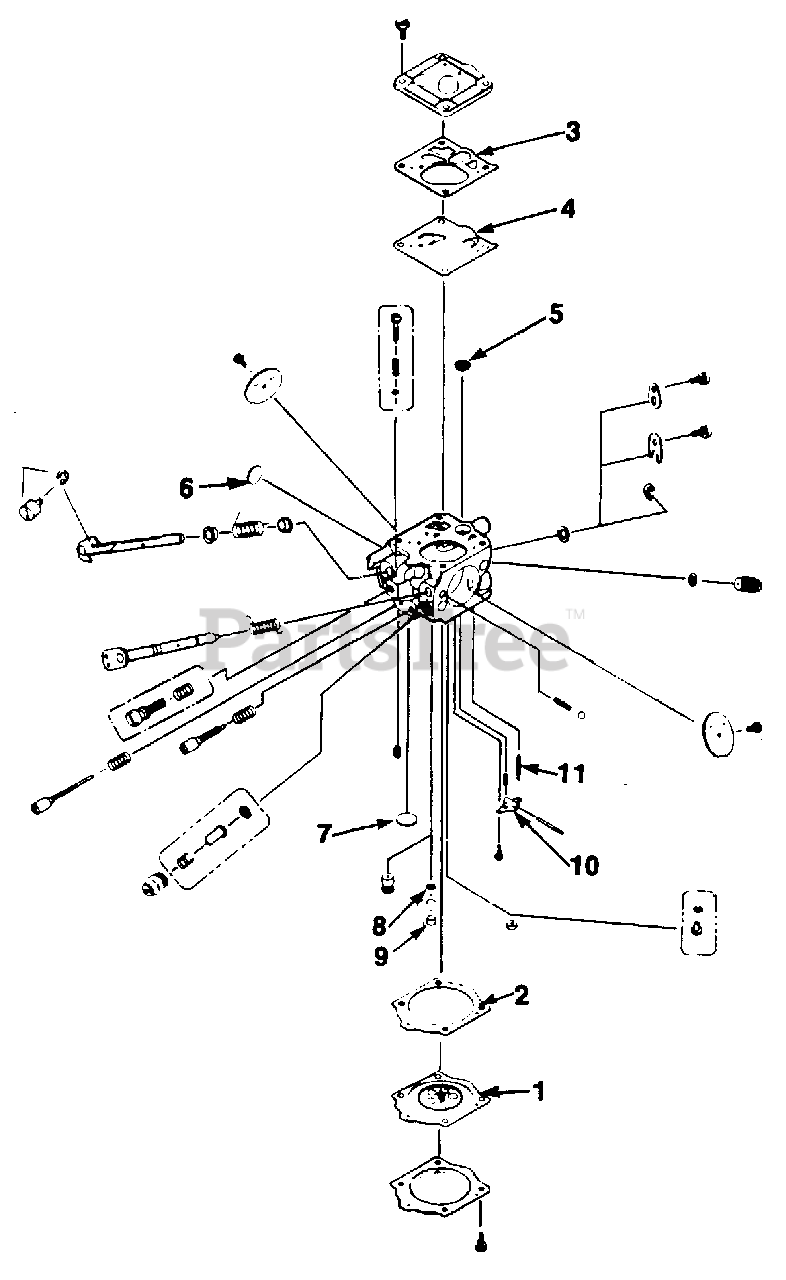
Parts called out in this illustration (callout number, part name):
1	Repair Kit (Includes 1-11)
2	Repair Kit (Includes 1-11)
3	Repair Kit (Includes 1-11)
4	Repair Kit (Includes 1-11)
5	Repair Kit (Includes 1-11)
6	Repair Kit (Includes 1-11)
7	Repair Kit (Includes 1-11)
8	Repair Kit (Includes 1-11)
9	Repair Kit (Includes 1-11)
10	Repair Kit (Includes 1-11)
11	Repair Kit (Includes 1-11)
